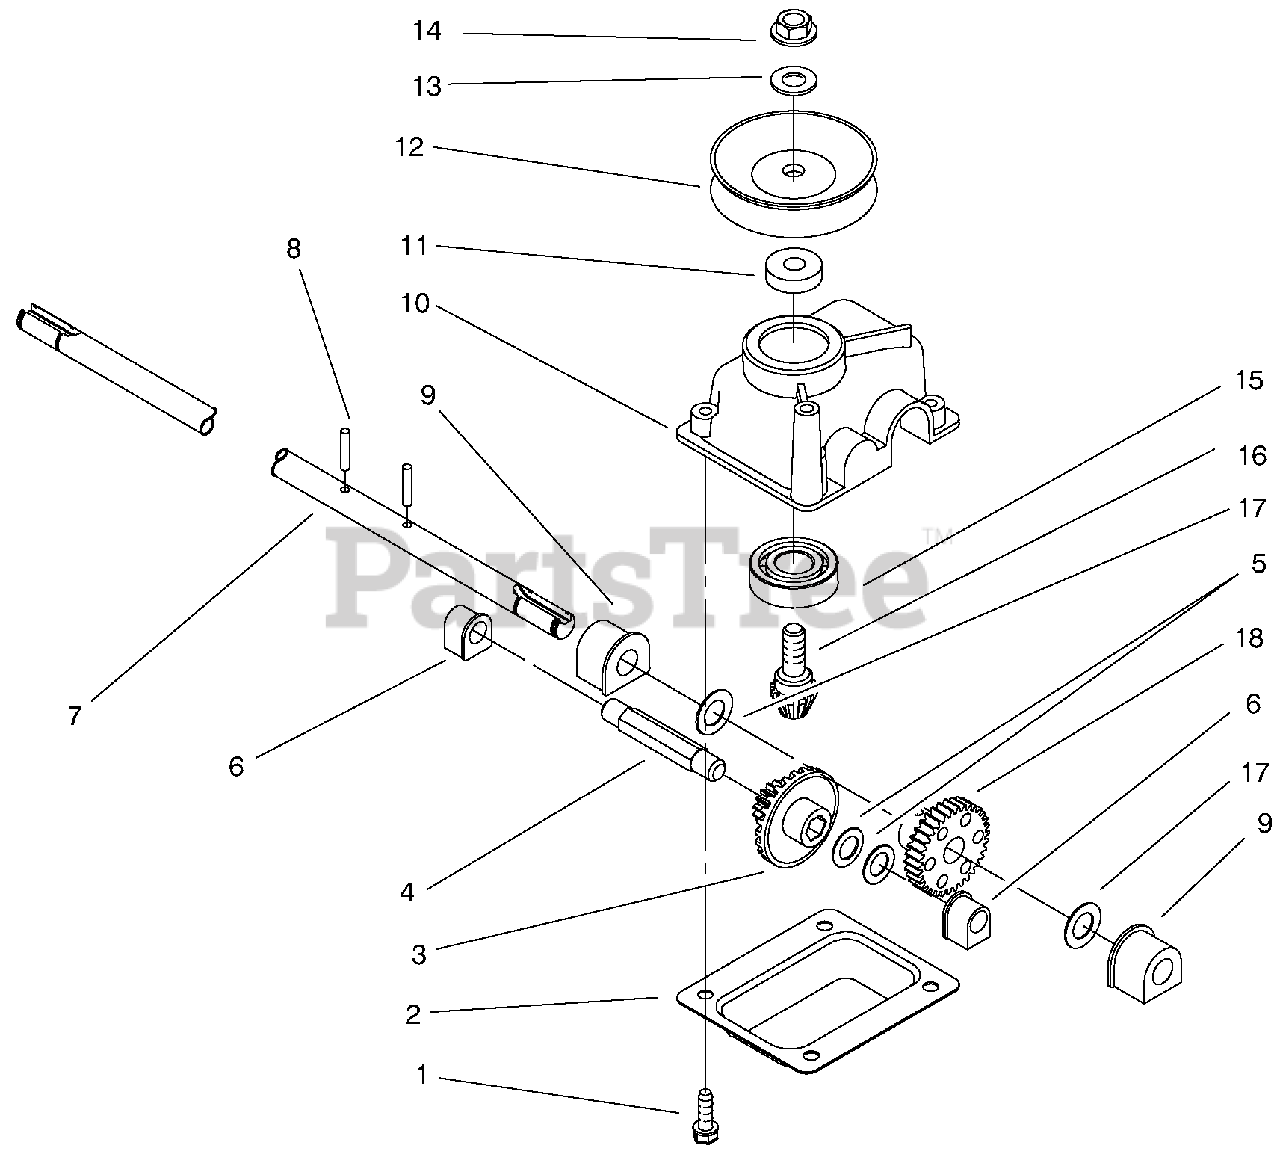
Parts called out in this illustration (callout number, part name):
1	Screw-Taptite
2	Cover-Gear Case
3	Pinion-15 Tooth
4	Shaft-Intermediate
7	Shaft-Output
8	Pin-Groove
9	Bushing-Output
10	Gearcase
12	Pulley-Half
15	Bearing-Ball
16	Gear-Bevel Pinion
17	Washer-Thrust
18	Gear 34 Tooth
